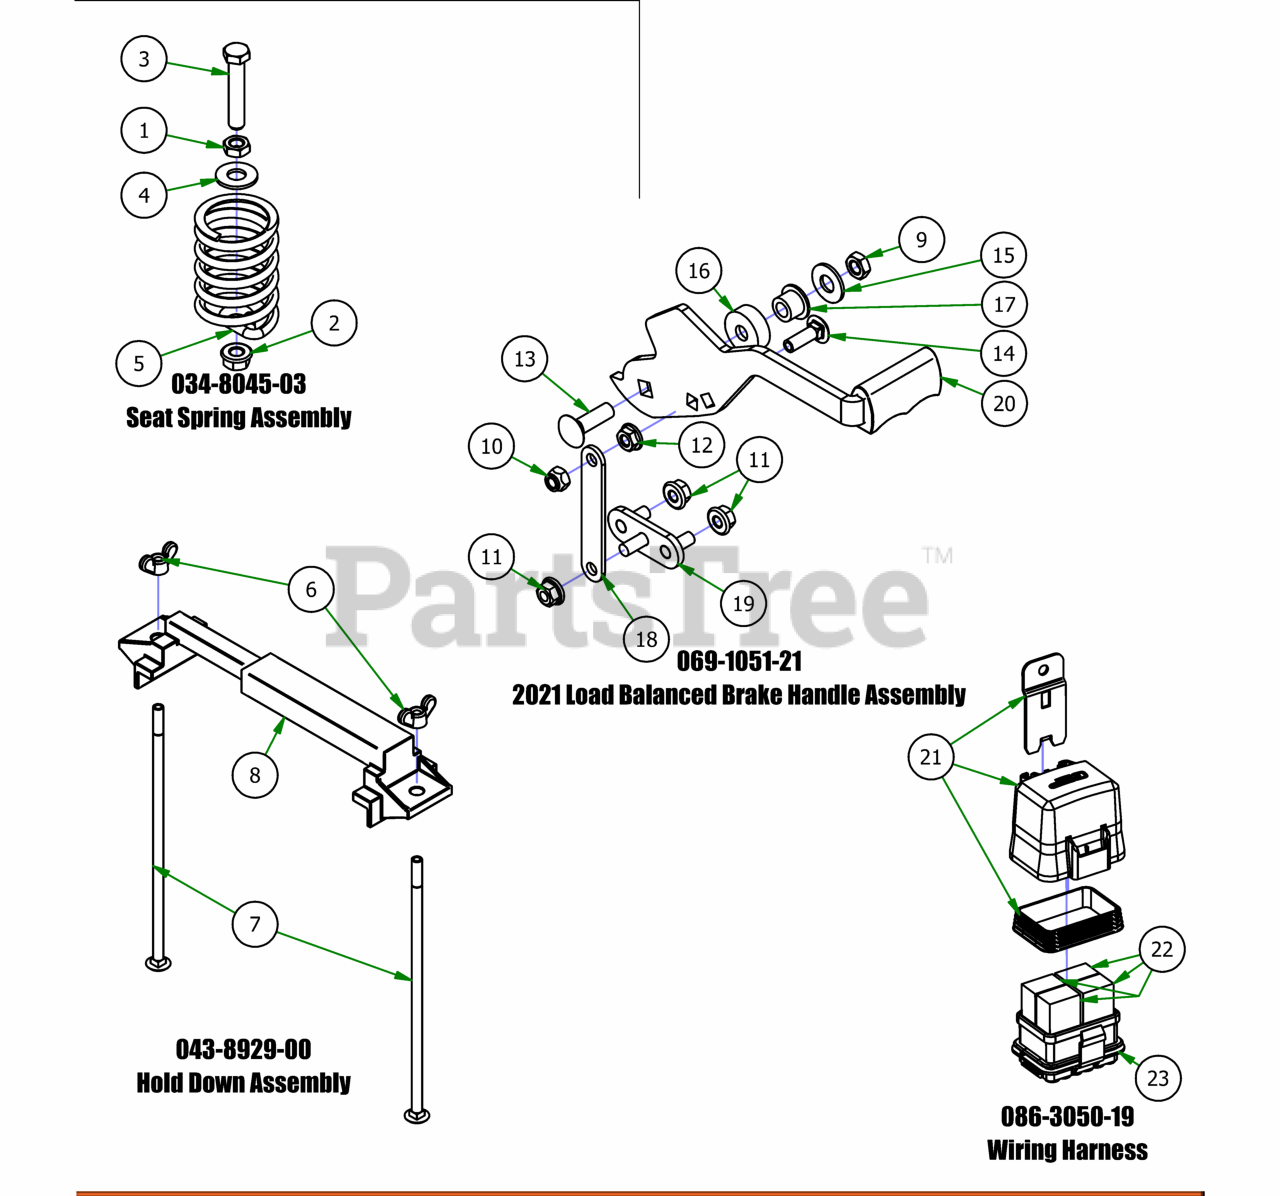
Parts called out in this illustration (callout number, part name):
1	3/8-16 Half Jam Nut
2	3/8-16 HEX SERRATED FLANGE NUT HARD/ZINC
3	3/8-16 X 2 HEX CAP SCREW (GR.5) ZINC
4	3/8 FLAT WASHER USS (1" OD) ZINC
5	Seat Spring
6	1/4" Wing Nut
7	1/4-20 X 8 Carriage Bolt
8	Battery Hold Down
9	3/8-16 HEX JAM 2-WAY REVERSIBLE CENTER LOCKNUT ZINC
10	5/16-18 NYLON INSERT CAP LOCKNUT ZINC (BLK CAP)
11	5/16-18 NYLON INSERT FLANGE LOCKNUT ZINC
12	5/16-18 HEX SERRATED FLANGE NUT HARD/ZINC
13	3/8-16 X 1-1/4 CARRIAGE BOLT ZINC
14	5/16-18 X 1 CARRIAGE BOLT (GR.8) ZINC
15	3/8 FLAT WASHER USS (1" OD) ZINC
16	2015 Brake Lever Spacer
17	.377 ID X .625 OD X .500 HGT X .880 FLNG DIA X .060 FLNG THK
18	Brake Cable Extension Plate
19	Brake Load Balancer Lower Weldment
20	Load Balanced Brake Handle with Grip
21	Relay Block Cover Replacement Kit
23	Wiring Harness (Includes Cover Replacement Kit and Relays)
